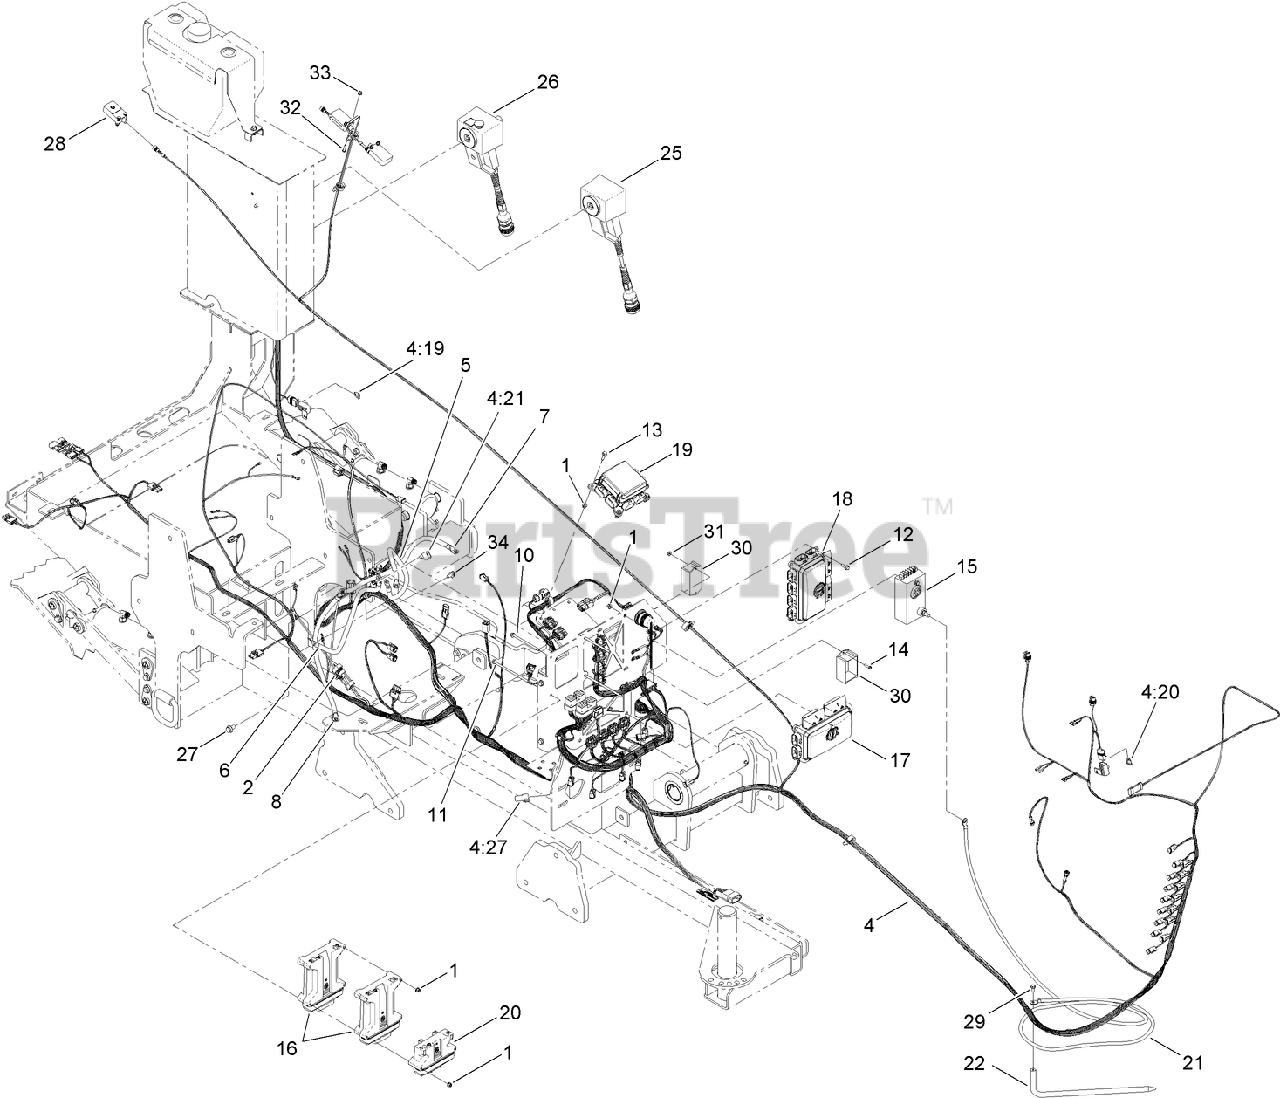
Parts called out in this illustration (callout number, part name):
1	NUT-FLANGE, NI
2	HARNESS-WIRE, FUSIBLE LINK
4	HARNESS-WIRE, MAIN
4:19	FUSE-BLADE, 10 AMP
4:20	FUSE-BLADE, 5 AMP
4:27	RESISTOR-120 OHM
5	CABLE-BATTERY, POSITIVE
6	CABLE-BATTERY, POSITIVE
7	CABLE-BATTERY, NEGATIVE
8	CABLE-BATTERY, NEGATIVE
10	SCREW-HHF
11	SCREW-HHF
12	SCREW-HHF
13	SCREW-HHF
14	SCREW-HWH
16	CONTROLLER-MICRO, 50-PIN
17	BOX-VEC, MAIN (A)
18	BOX-VEC, MAIN (B)
19	BOX-VEC, MAIN (C)
20	COMPUTER-EXPANDER, OUTPUT
21	CABLE-ALERT, STRIKE
22	BAR-STAKE, GROUND
25	LIFE JACKET ASM
26	TRAVEL PENDANT ASM
27	SCREW-HHF
28	SWITCH-PROXIMITY
29	SCREW-HHF
30	CONNECTOR-PACK, RESISTOR
31	NUT-LOCK, FLANGE
32	SCREW-HSH
33	NUT-HF
34	CLIP-TREE (W/TIE)
